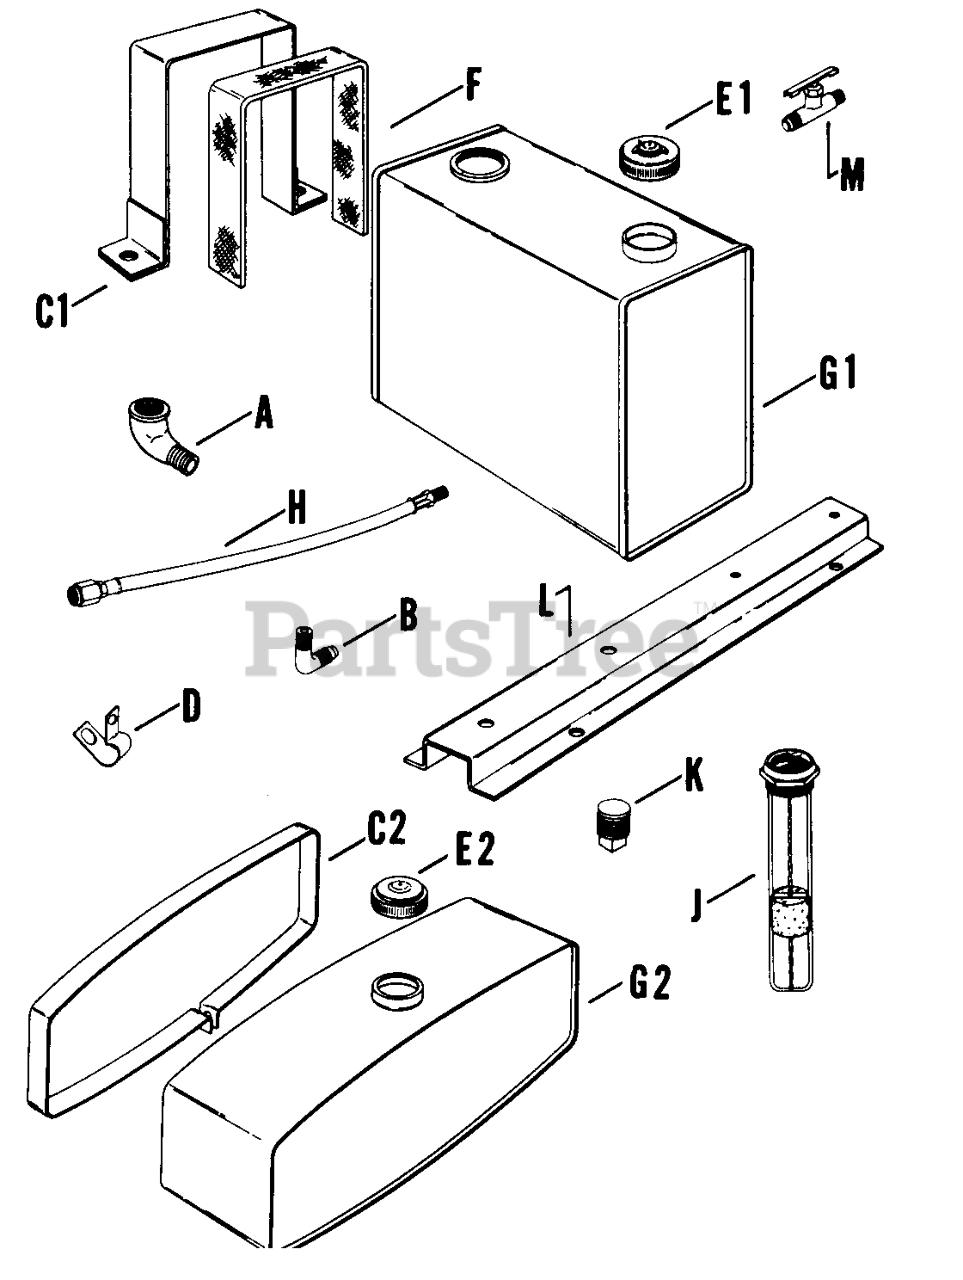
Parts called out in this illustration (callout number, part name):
A	ELBOW - USE 48 283 03
D	Clip, fuel line
M	Valve, fuel shut-off
